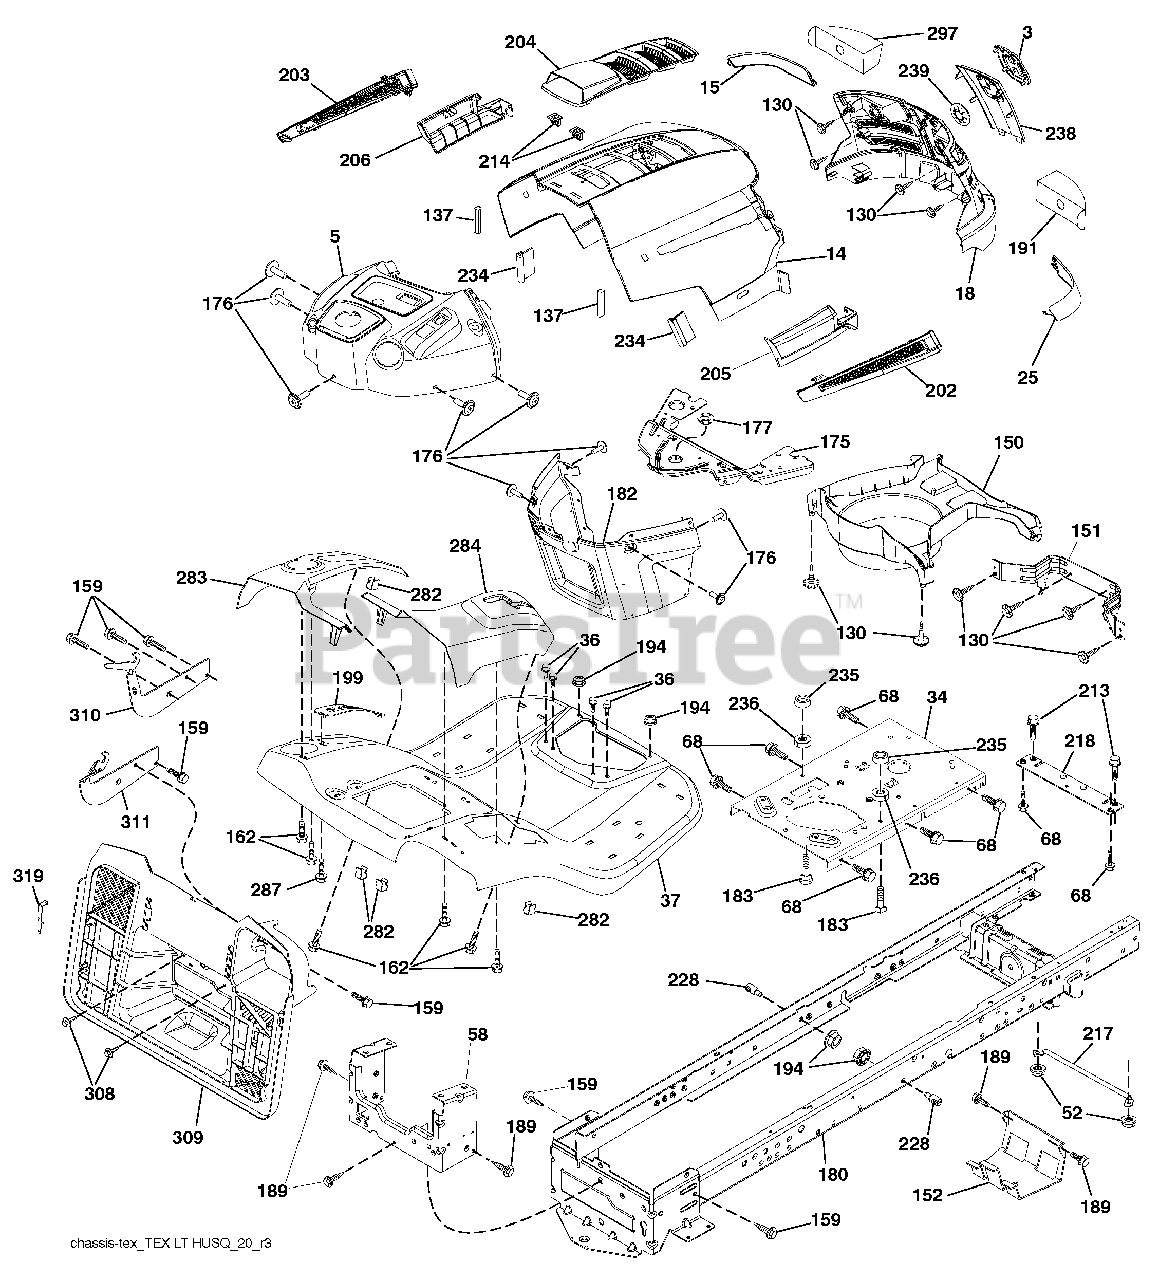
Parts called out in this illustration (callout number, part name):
3	Logo
5	Dash
14	Hood
15	Lens LH
18	Grille
25	Lens RH
34	Plate Engine
36	Screw 5/16-18 x 3/4
37	Fender
52	Nut Crown Lock 5/16
58	Drawbar Upper
68	Screw Thdrol. 5/16-18 x 1/2
130	Screw #10 x 0.750 BOS Thread
137	Bumper Dash
151	Bracket Pivot
152	Shield Browning
159	Screw Kexwsh Thdr 3/8-16 x 3/4
162	Screw Hex Wsh. Hi-Lo 1/4 x 1/2 unc
175	Crossmember
176	Screw 10-24 x 5/8
177	Bushing Steering
180	Chassis
182	Dash Lower
183	Bolt 5/16-18 unc x 1-1/4
189	Screw 5/16-18 x 3/4
191	Insert Reflective RH
194	Nut Lock Hex Flange 5/16-18
199	Plate Deck Lift
202	Vent Side Hood RH
203	Vent Side Hood LH
204	Vent Top Hood
205	Skirt Side RH
206	Skirt Side LH
213	Bolt 5/16-18 x 3/4
214	Clip Retainer
217	Rod Pivot Hood
218	X-Piece Hood Stop
228	Stud Fastener
234	Bumper Hood
235	Spacer Fender
236	Nut Lock 5/16-18 unc
238	Trim
239	Clip Tinnerman
282	Clip Retainer
283	Console Deck Lift
284	Console Shift
287	Screw Hex Washead 1/4-20 x 3/8
297	Insert Reflective LH
308	Bolt 5/16-18 unc x 3/4
309	Backplate Bagger SRD
310	Bracket Hangar Bag LH
311	Bracket Hangar Bag RH
319	Bracket Actuator
